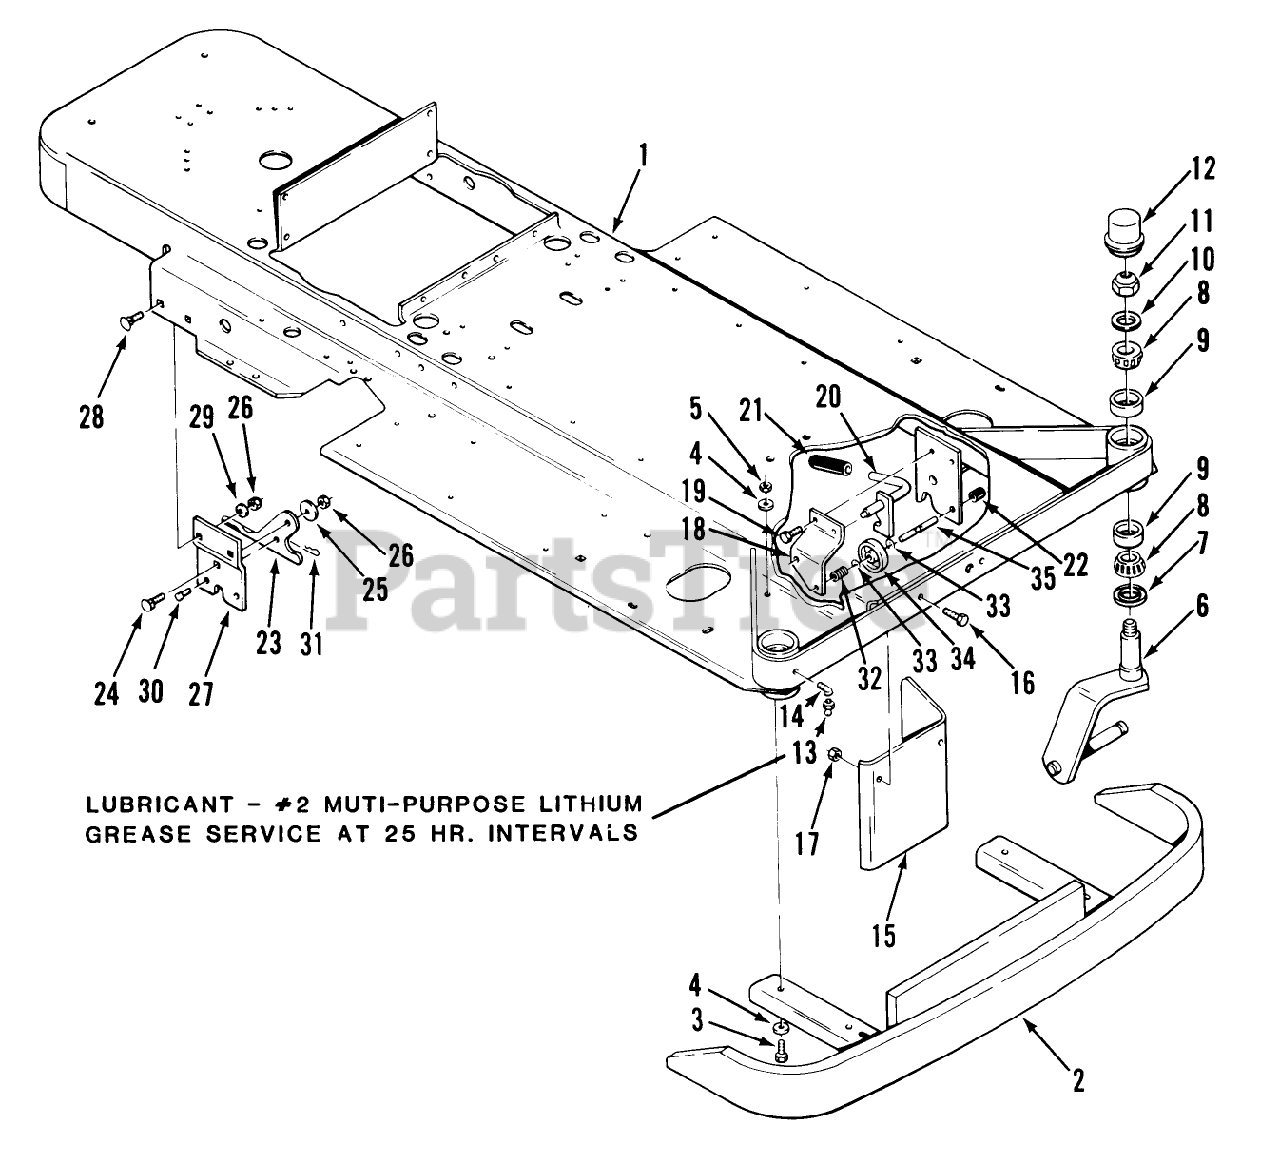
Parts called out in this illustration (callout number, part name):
4	SAE Washer3/8
12	DUST CAP
19	Screw
21	GRIP
22	CAP-ROD, PLUNGER
23	PLATE-LATCHING
31	Hairpin
32	SPRING
33	RING-RETAINING
35	ROD-LOCK
